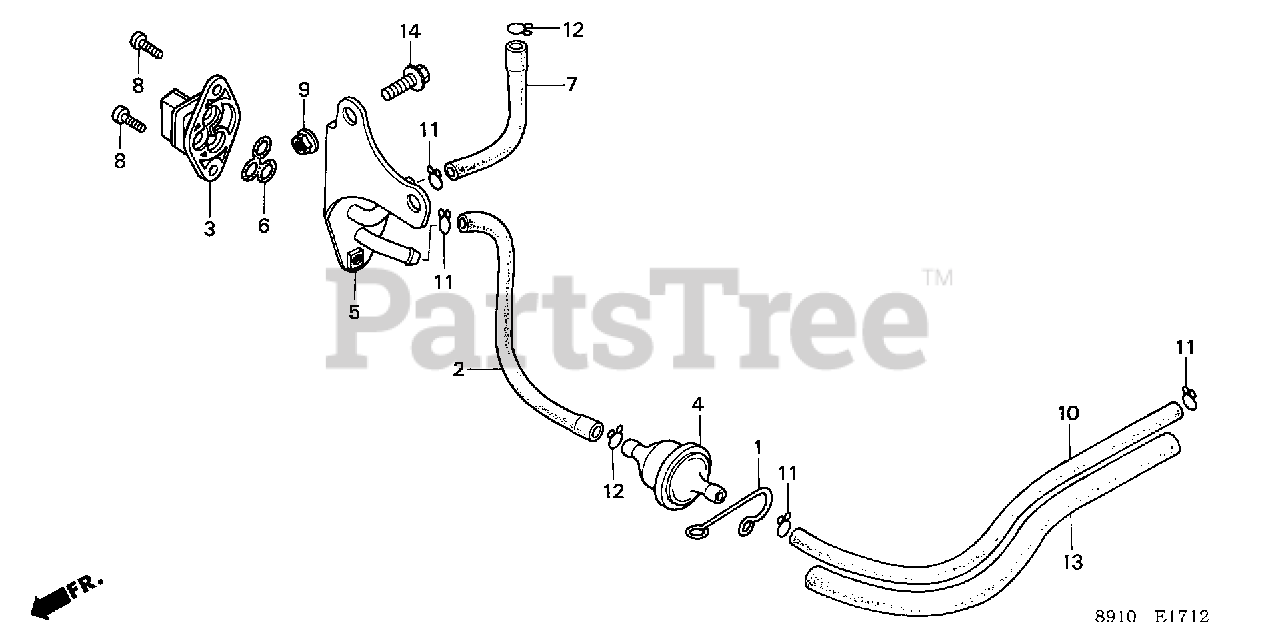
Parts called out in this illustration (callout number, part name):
1	CLAMP, FUEL TUBE Use from Engine SN 2086984.
2	TUBE, FUEL TANK Use from Engine SN 2086984.
3	PETCOCK ASSY. Use from Engine SN 2086984.
4	FILTER, FUEL Use from Engine SN 2086984.
5	STAY, PETCOCK Use from Engine SN 2086984.
6	GASKET Use from Engine SN 2086984.
7	TUBE, FUEL (5.3X105) Use from Engine SN 2086984.
8	SCREW, PAN (6X14) Use from Engine SN 2086984.
9	NUT, FLANGE (6MM) Use from Engine SN 2086984.
10	BULK HOSE, FUEL (5.5X3000) Use from Engine SN 2086984.
11	CLIP, TUBE (B10) Use from Engine SN 2086984.
12	CLIP, TUBE (B12) Use from Engine SN 2086984.
13	BULK HOSE, VACUUM (11X1000) Use from Engine SN 2086984.
14	BOLT, FLANGE (6X12) Use from Engine SN 2086984.
